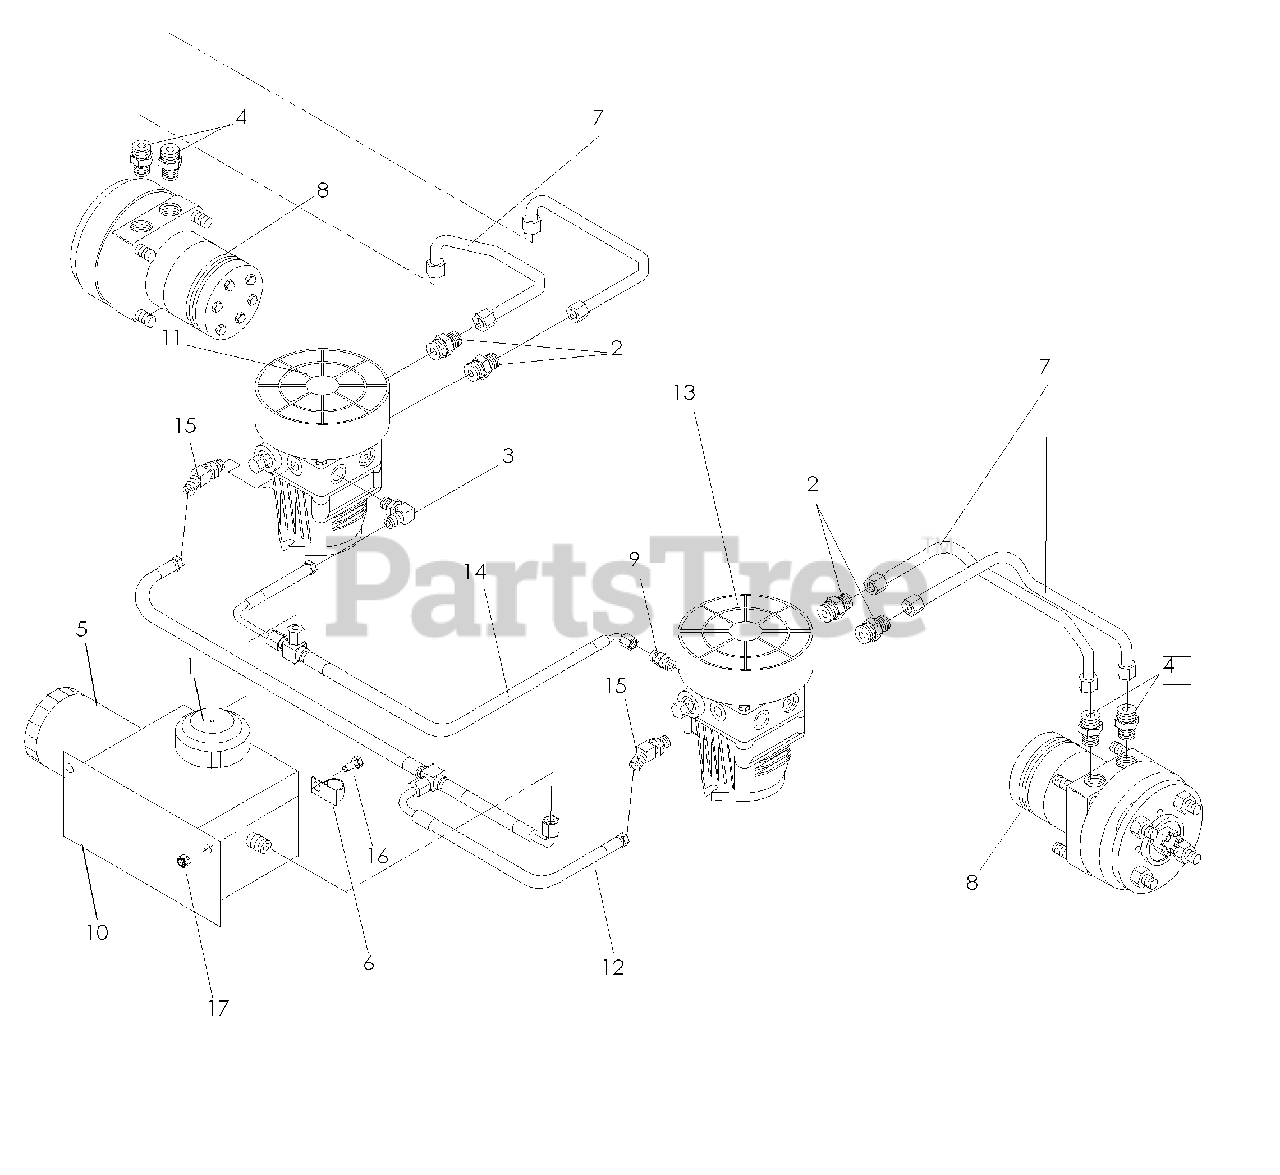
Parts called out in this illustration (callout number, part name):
1	HYDRAULIC CAP
2	FITTING, STRAIGHT F6400-8-8-0
3	ELBOW, F6801-6-6-0 90 DEGREE
4	FITTING
5	HYDRAULIC OIL FILTER
6	LOOM CLIP
7	RUBBER HYDRAULIC HOSE (1)
8	TL15 WHEEL MOTOR
9	Hydraulic Fitting
10	RESERVOIR W/CAP & FILTER
11	10CC PUMP W/6" FANS RH
12	T-ASM, INLET
13	10CC PUMP W/6" FANS LH
14	T-ASM, RETURN
15	FITTING, HYDR 45 DEG
16	HCS 5/16C X 3/4
17	NUT 5/16 NYLOC
